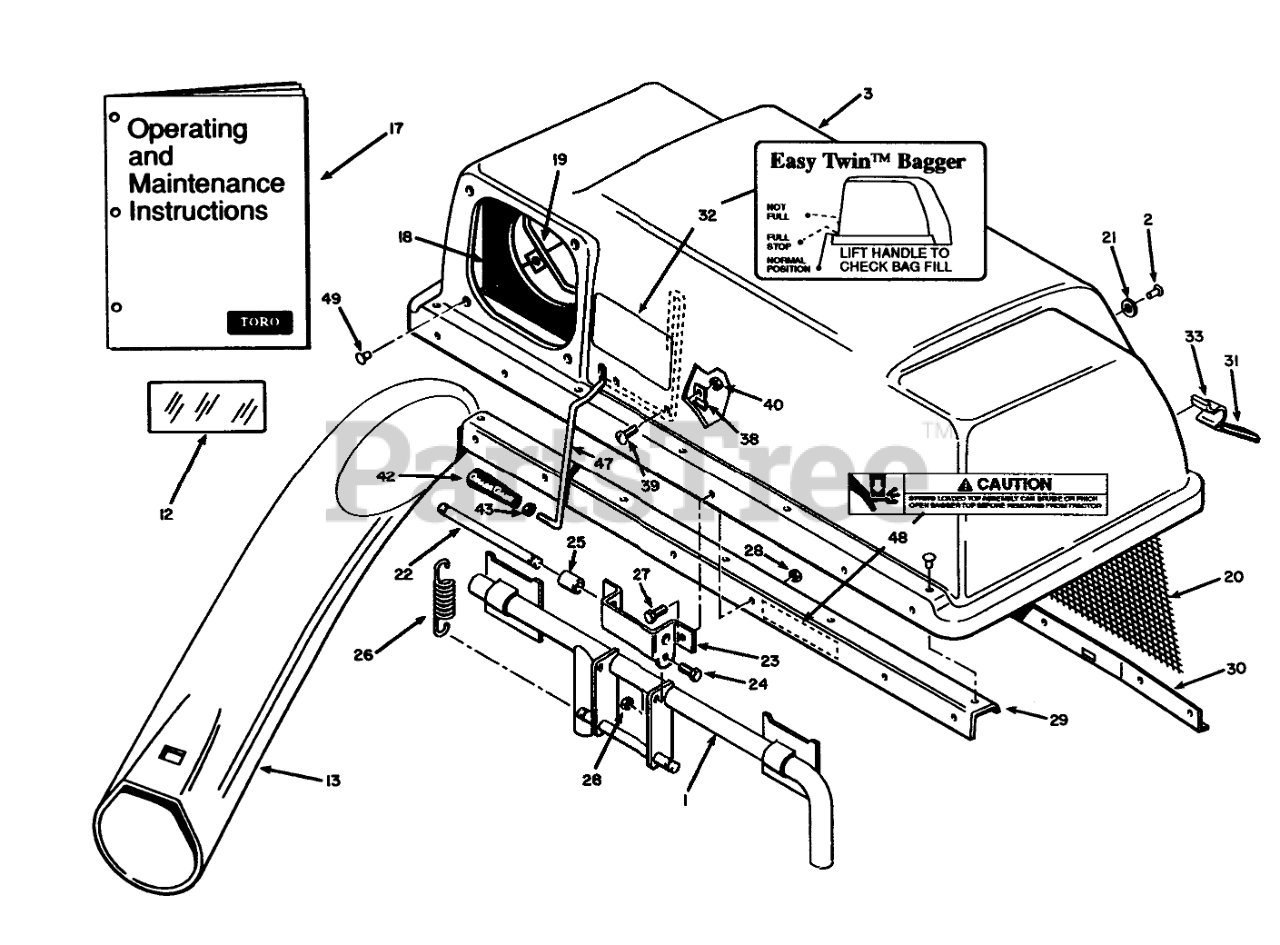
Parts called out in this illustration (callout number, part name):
1	FRAME ASM
2	RIVET-BLIND
3	TOP-BAGGER
12	Decal-Vin Overlay
13	CHUTE-BAGGER
17	Operating & Maintenance Instructions
18	SEAL-CHUTE
19	CLAMP-SEAL
20	SCREEN-BAGGER
21	Washer
22	PIN-SPRING
23	HINGE-BAG TOPB
24	Bolt
25	SPACER
26	SPRING-EXTENSION
27	BOLT
28	NUT
29	Bagger-Stiffener
30	SUPPORT-SCREEN B
32	DECAL
33	Latch-Bag
38	Clip
39	Screw
40	Nut
42	HANDLE-TAPERED
43	Nut
47	FEELER-FILL, BAG
48	DECAL-CAUTION
49	Pop Rivet
